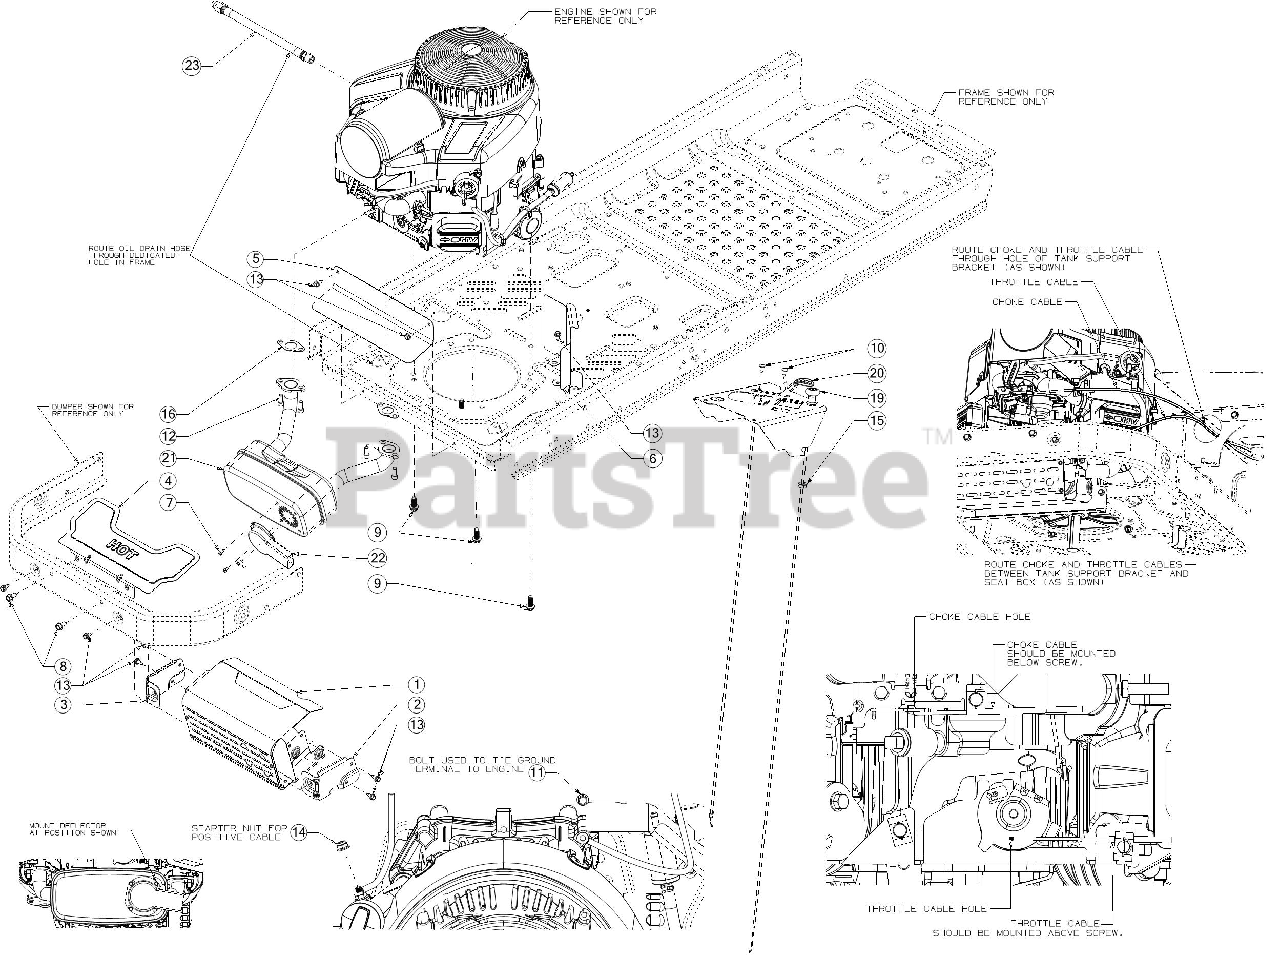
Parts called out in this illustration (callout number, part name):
1	MUFFLER SHIELD W/EXTENSION
2	MUFFLER SHIELD BRACKET (RH)
3	MUFFLER SHIELD BRACKET (LH)
4	MUFFLER HEAT SHIELD
5	LOWER HEAT SHIELD
6	ENGINE HEAT SHIELD
7	HEX SCREW WASHER HD #8-18 x 0.500
8	SCREW 5/16-18 x .750
9	SCREW 3/8-16 x 1
10	SCREW 1/4-20 x .5
11	SCREW 1/4-20 X.500
12	SCREW 5/16-18 x .625
13	SCREW 1/4-20X.625
14	FLANGE LOCK NUT
15	HEX FLANGE NUT
16	MUFFLER GASKET
19	CHOKE CABLE 47"
20	THROTTLE CABLE 36"
21	EXHAUST MUFFLER(B&S)(TWIN)
22	EXHAUST DELECTOR
23	OIL DRAIN HOSE
